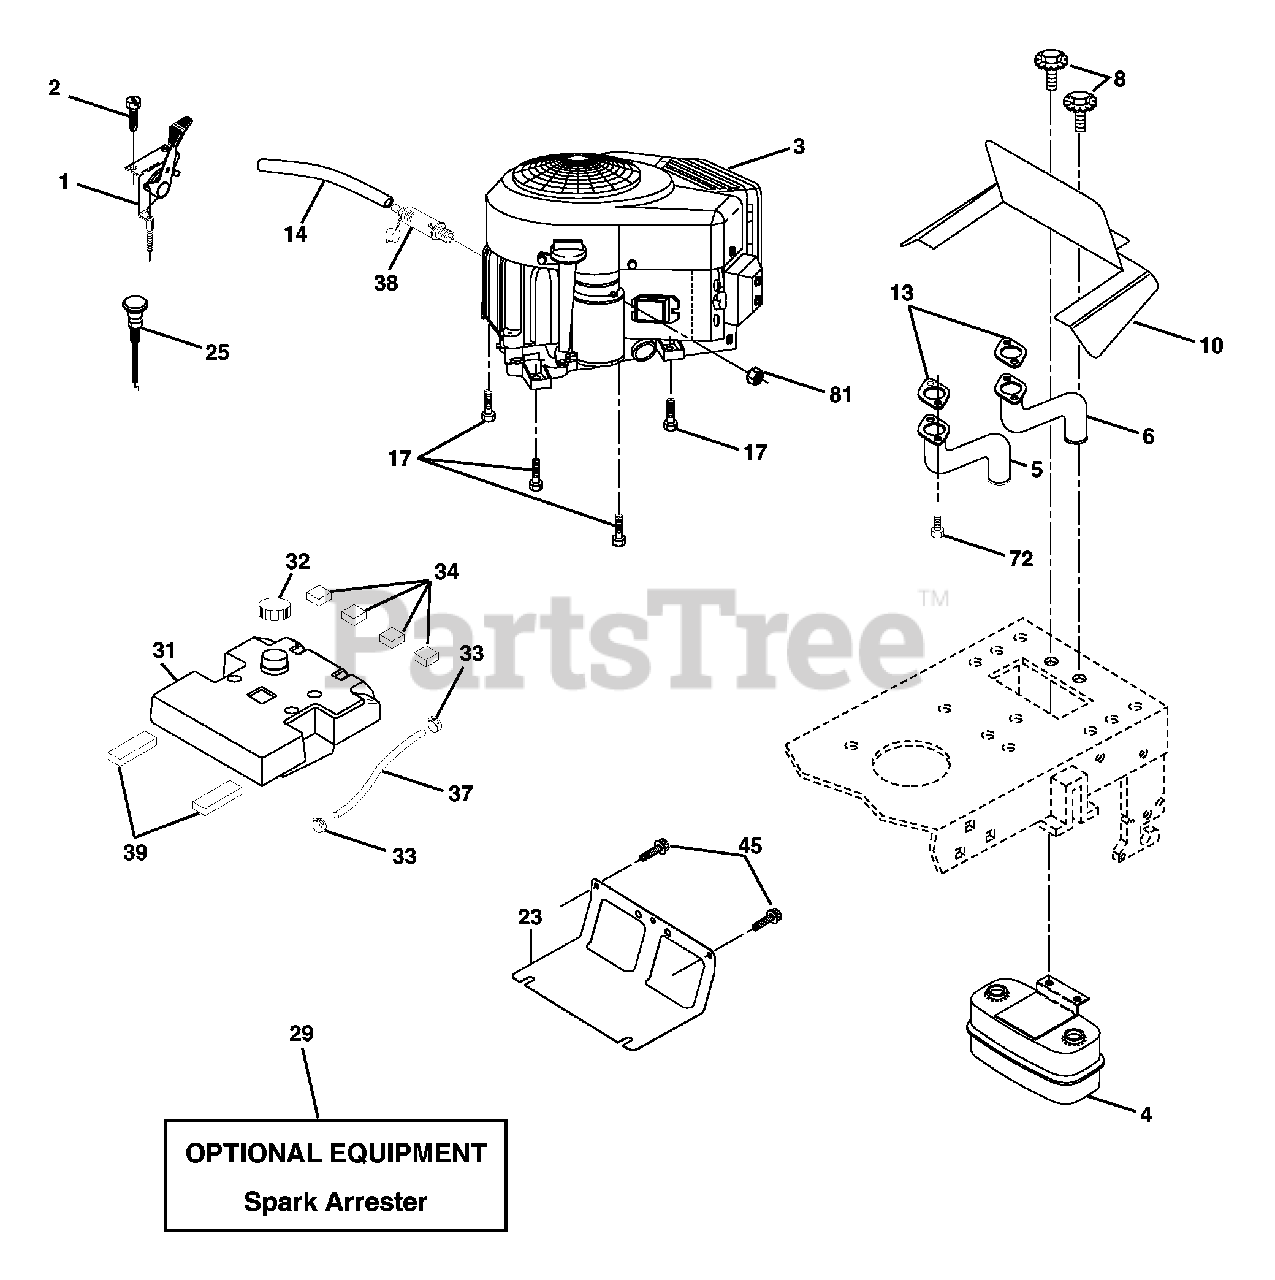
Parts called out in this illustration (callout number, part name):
1	Control, Throttle/Choke
2	Screw Hex Single Lead 10 x 3/4
4	Muffler
5	Tube Exhaust LH
6	Tube Exhaust RH
8	Bolt 5/16-18 unc x 3/4 w/Sems
10	Shield Browning
13	Muffler Gasket
14	Tube Oil Drain
17	Screw 3/8-16 x 1-1/2
23	Shield, Browning/Debris Guard
25	Control Choke
29	Arrester, Spark
31	Tank, Fuel
32	Cap Gauge, Fuel
33	Clamp, Hose Blk
34	Pad Spacer 1x1x1
37	Line, Fuel
38	Plug Drain Oil Easy
39	Pad Idler 1.75 x .75 x .06
45	Screw Hex Wsh Thdrol 3/8-16 x 3/4
72	Screw 5/16-18 x 1
81	Nut Keps Hex 1/4-20 unc
